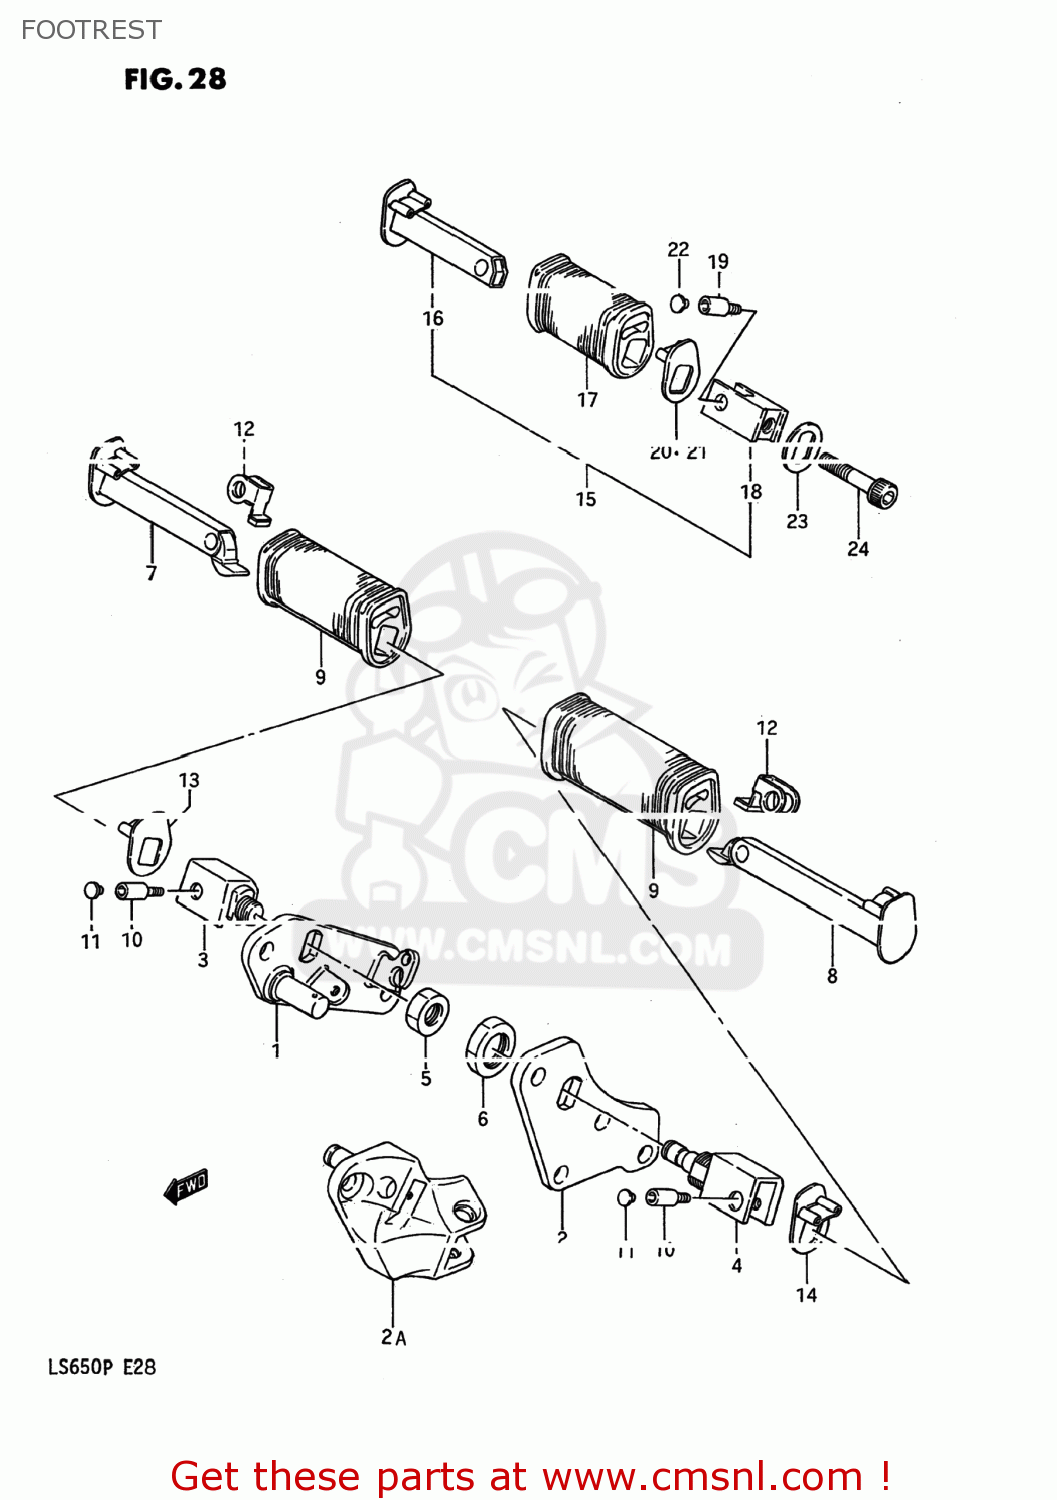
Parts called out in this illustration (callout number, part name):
1	BRACKET,FR FOOTREST,R
2	BRACKET,FRONT FOOTREST
2A	BRACKET,FRONT FOOTREST
3	HOLDER,FR FOOTREST,R
4	HOLDER,FR FOOTREST,L
5	NUT
6	NUT
7	BAR,FRONT FOOTREST,RIGHT
8	BAR,FRONT FOOTREST,LEFT
9	RUBBER,FR FOOTREST
10	BOLT,FRONT FOOTREST RUBBER
11	CAP,PILLION FOOTREST BOLT
12	CUSHION,FRONT FOOTREST
13	WASHER,FR FOOTREST,R
14	WASHER,FR FOOTREST,L
15	FOOTREST ASSY,PILLION,R
16	BAR COMP,PILLION FOOTREST
17	RUBBER,PILLION FOOTREST
18	BAR,PILLION FOOTREST
19	BOLT,FRONT FOOTREST RUBBER
20	WASHER,FR FOOTREST,R
21	WASHER,FR FOOTREST,L
22	CAP,PILLION FOOTREST BOLT
23	WASHER,PILLION FOOTREST HOLDER
24	BOLT 10X45
